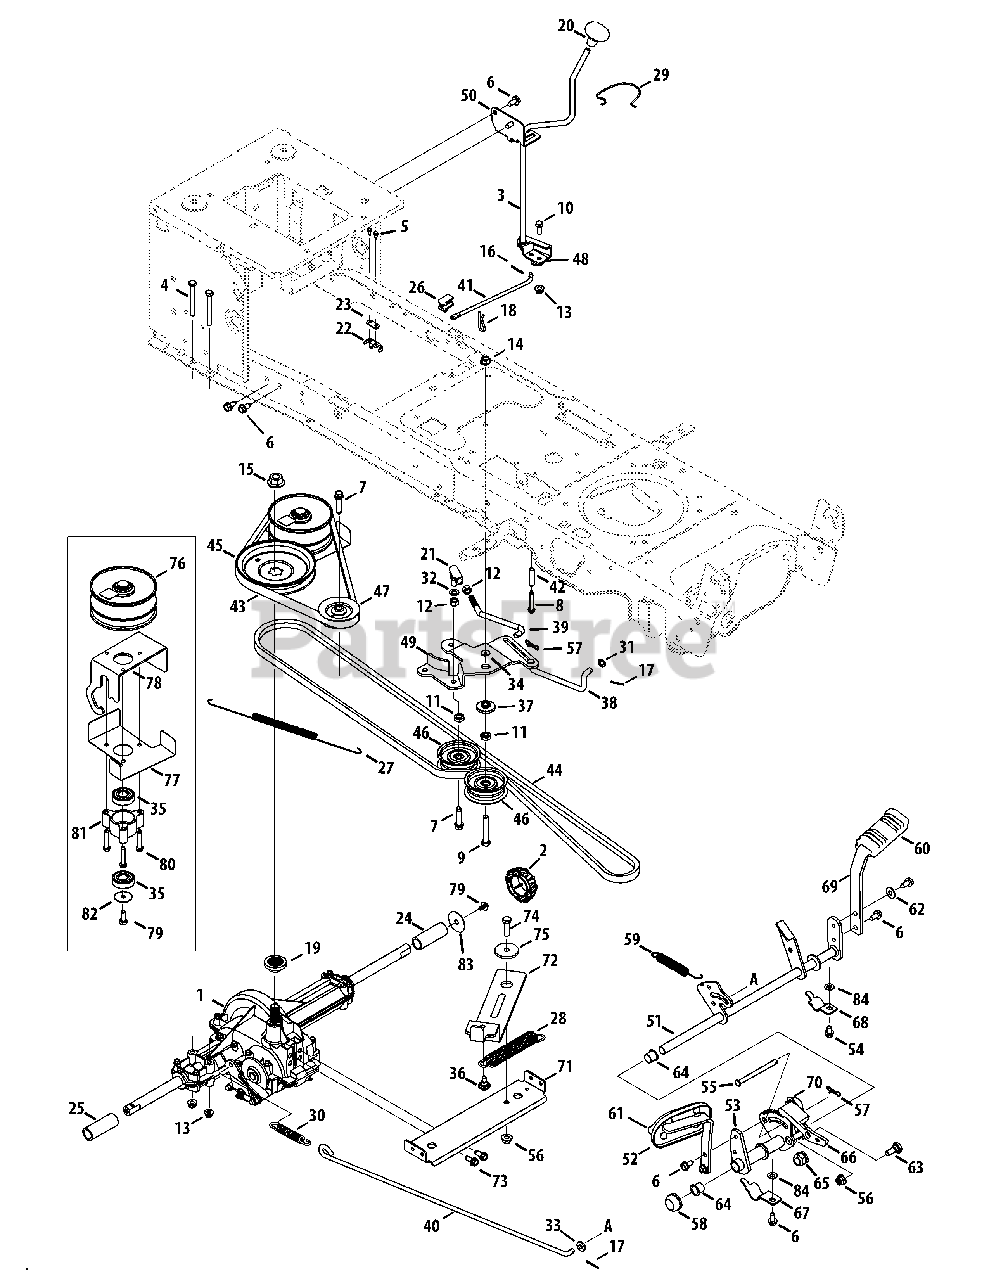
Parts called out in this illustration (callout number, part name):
1	Transaxle Ass’y
2	Cap, Hub
3	Lever Ass’y, Shift
4	Hex Screw, 5/16-18, 2.75, Gr5, Std
5	Screw, Ab, #8-18, 0.500,
6	Screw, Self-tapping, 5/16-18, .750,
7	Screw, Sems, 3/8-16, 1.500
8	Screw, Self-tapping, 1/4-20, 1.750,
9	Hex Screw, 3/8-16, 2.25, Gr5, Std
10	Hex Screw, 5/16-18, .625, Gr5, Std
11	Nut, Jam, 7/16-20, Gr2
12	Nut, Hex, 3/8-24, Gr5
13	Nut, Flange Lock, 5/16-18, Grf
14	Nut, Flange Lock, 3/8-16, Grf
15	Nut, Flange, 9/16-18, Gr2
16	Pin, Cotter, .072 Dia. x 1.13
17	Pin, Cotter, 3/32, 1.0
18	Pin, Cotter Internal, .125 Dia
19	Hub, Pulley, 5/8 Spline
20	Knob, Shift
21	Ball, Joint
22	Switch, Spring, Short
23	Plate, Insulator Nut
24	Sleeve, .758 x .821 x 3.3125
25	Sleeve, .758 x .821 x 2.4375
26	Bearing, Shift Plate
27	Spring, Extension, .70 Dia x 12.00
28	Spring, Extension, .97 OD x 6.18
29	Clip, Spring, Shifter
30	Spring, Extension, .59 OD x 4.00
31	Washer, Flat, .385 x .62 x .063
32	Washer, Lock, 3/8, Regular Duty
33	Washer, Flat, .344 x .750 x .120
34	Wash, Flat, .385 x 1.00 x .03
35	Bearing, Ball, 17x40x12, 6203, Ds
36	Screw, Shoulder, .43x.29, 5/16-18
37	Spacer, Shoulder, 1.375 x .380 x .183
38	Rod, Footpedal Bypass
39	Rod, Adjustment, Idler, 3/8
40	Rod, Brake
41	Rod, Shift,
42	Spacer, .260 x .372 x 1.420
43	Belt, V-Type, Poly
44	Belt, V-Type, Poly
45	Pulley, V-Type, 7.25 Dia Spun
46	Pulley, Idler, Flat 2.75 OD
47	Pulley, Idler, V-Type x 3.06
48	Bracket, Shift, Adjustment
49	Bracket, Idler, Center Double
50	Bracket, Shift, F-N-R
51	Control Ass’y, Brake
52	Ped Ass’y, Control, Auto Drive
53	Bracket Ass’y, Pedal
54	Screw, Self-tapping, 5/16-18, 0.625,
55	Pin, Clevis, 5/16 x 3.985
56	Nut, Flange Lock, 3/8-16, Grf,
57	Pin, Cotter, Bow-Tie 72
58	Cap, Push 5/8
59	Spring, Extension, .63 Dia x 4.95
60	Pad, Pedal, Brake
61	Pad, Control
62	Washer, Bell, .340 x .872 x .060
63	Bolt, Shoulder, .500 x .270, 3/8-16
64	Bearing, Flange
65	Bearing, Hex Flange, .628 ID, Split
66	Latch, Cruise
67	Bracket, Support, Pedal Strap
68	Bracket, Support, Pedal Strap 5/8
69	Bracket, Ped, Brake
70	Plate, Bracket, Reinforcement
71	Bracket Ass’y, Transmission
72	Bracket Ass’y, Idler
73	Screw, Self-tapping, 5/16-18, 0.750,
74	Hex Screw, 3/8-16, 1.25, Gr5, Std
75	Spacer, Shoulder, .8840 x .190
76	Pulley Ass’y, Var Spd, 4.75 OD
77	Keepr Ass’y, Belt
78	Bracket Ass’y, Variable
79	Screw, 5/16-24 x .750
80	Screw, Self-tapping, 1/4-20, 1.500,
81	Cup, Bearing
82	Washer, Flat, .330 x 1.25 x .06,
83	Washer, Flat, .350 x 1.59 x .062
84	Flat Washer, .344 x .688 x .065
